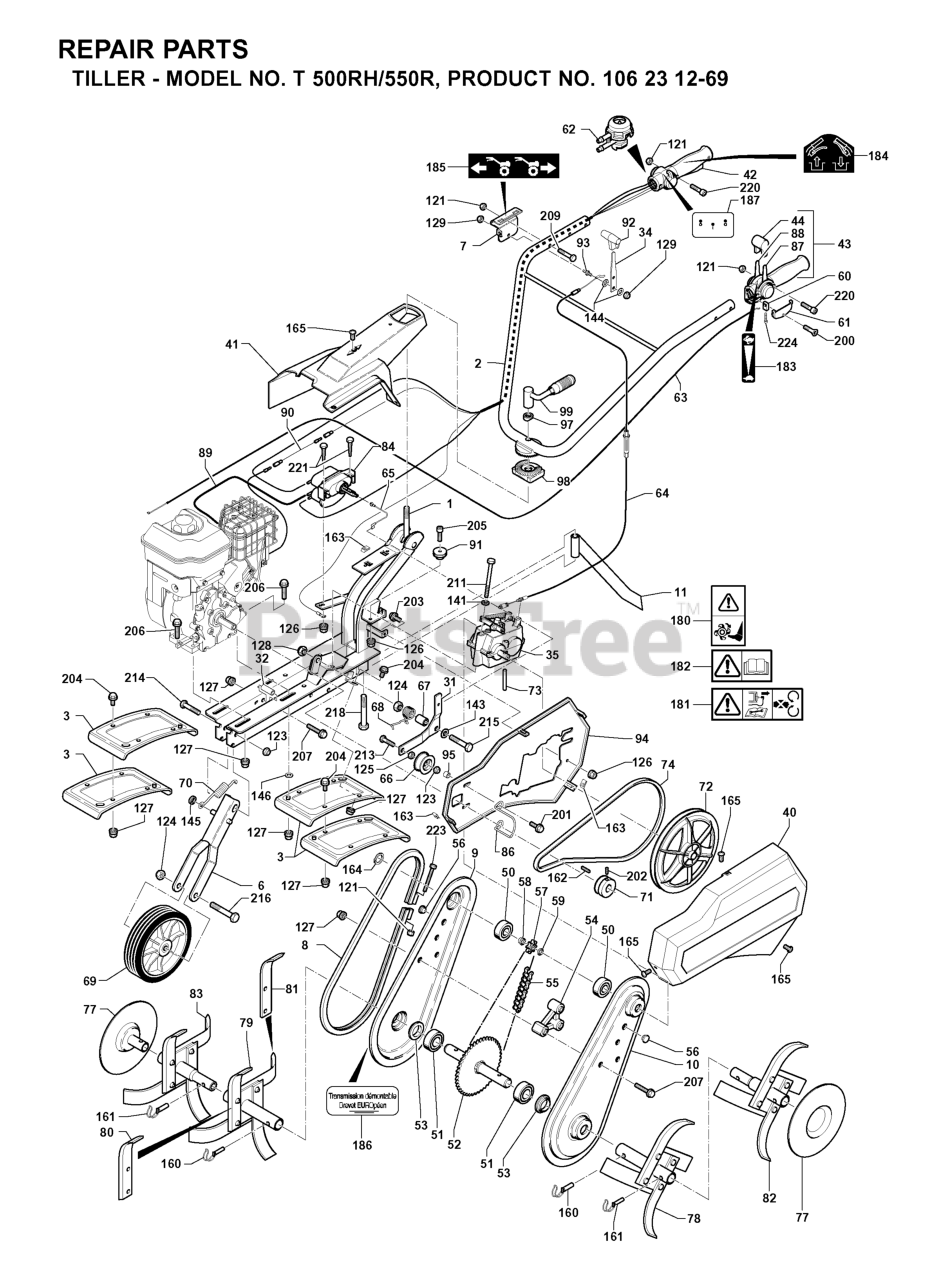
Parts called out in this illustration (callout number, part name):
31	ARM
53	SPACER SLEEVE
55	DRIVE CHAIN
63	REPL BY 519 00 64-26
69	WHEEL
121	Blocking nut M 6 Z
164	RETAINING RING
